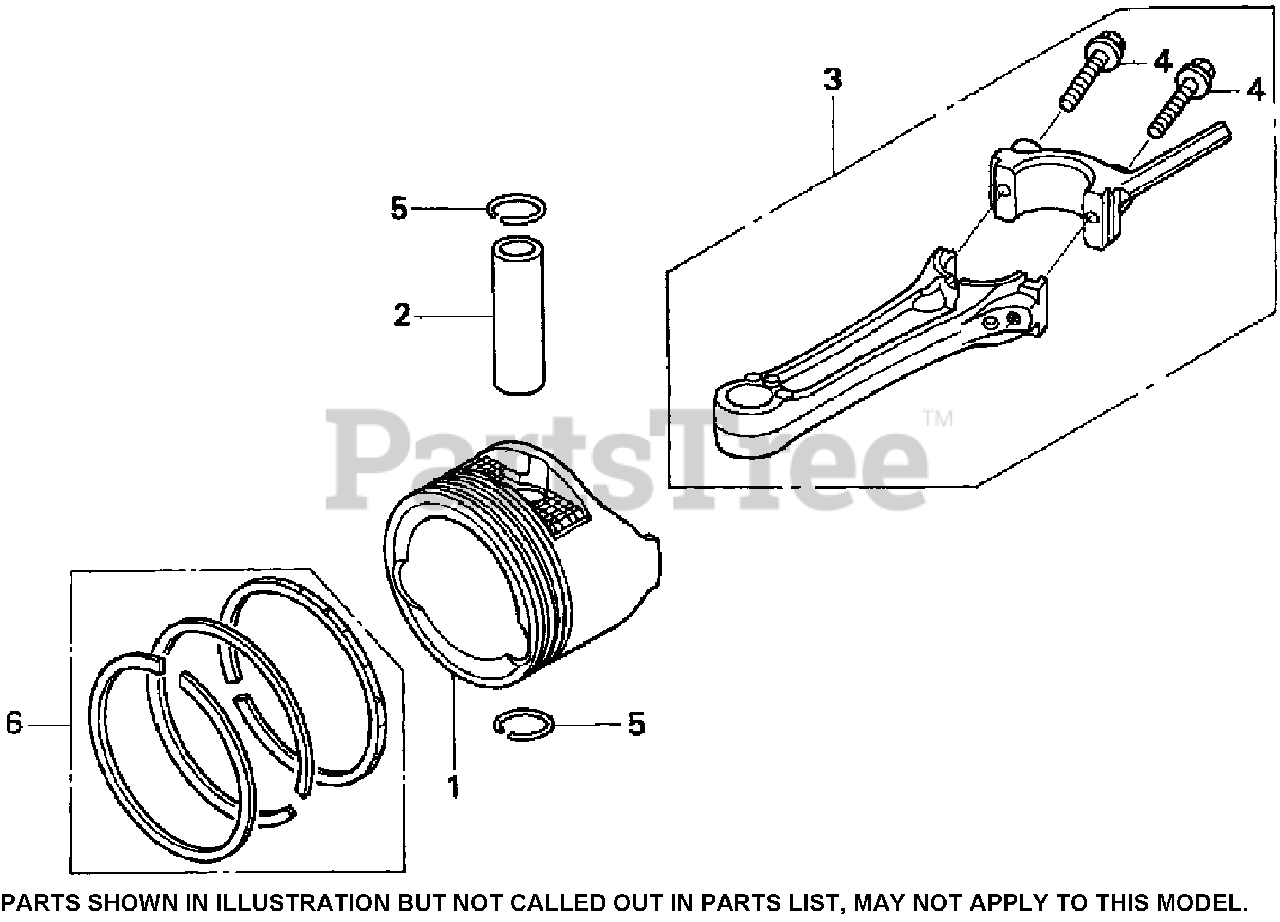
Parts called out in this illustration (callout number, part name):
1	PISTON
2	PIN-PISTON
3	CONNECTING ROD ASM
4	BOLT-ROD, CONNECTING
5	CLIP-PIN, PISTON (13MM)
6	RING SET-PISTON (RIKEN)
